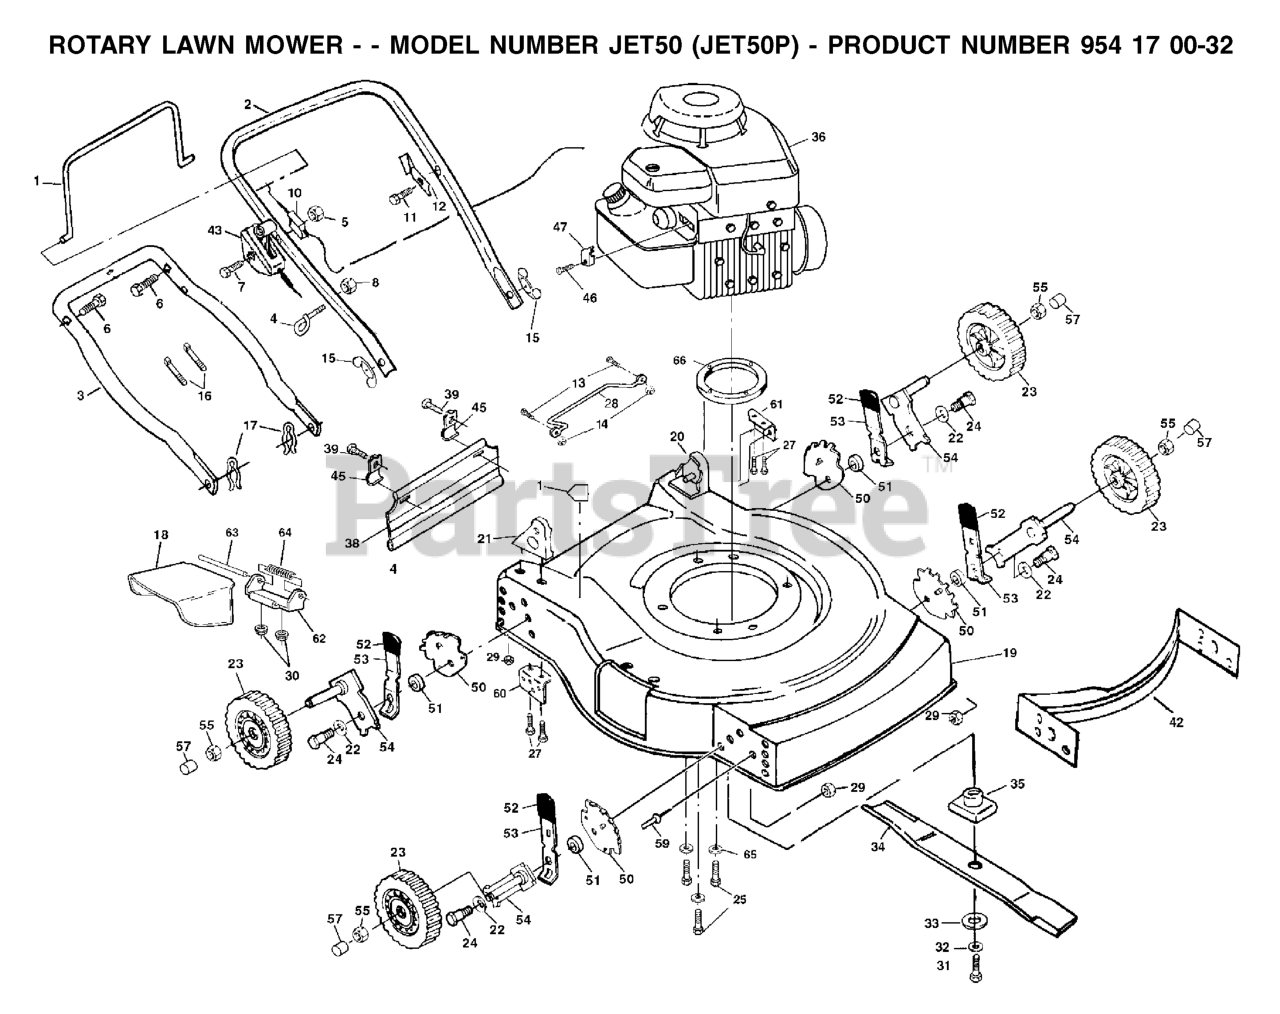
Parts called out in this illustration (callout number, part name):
1	CONTROL BAR
2	UPPER HANDLE
3	HANDLE
4	ROPE, GUIDE
5	NUT
6	HANDLE BOLT
7	SCREW 1/4-20 X 2.12
8	NUT
10	CABLE.MZR.51.RT.SP./PU.
11	TAPPING SCREW
12	BRACKET UPSTOP
13	REPL BY 817 02 10-08
15	NUT WING PM
16	TIE GUIDE
17	HAIRPIN COTTER
20	HANDLE BRACKET ASM. LH
21	HANDLE BRACKET ASM. RH
22	WASHER.BELLEVILLE (3 2 LB)
23	WHEEL
24	BOLT
27	SCREW.5/16-18X3/4
29	LOCKNUT PM
30	NUT
31	SCREW, HEX HD 3/8-24 X 1-3/8
32	LOCKWASHER
33	WASHER,HARDEN
34	20" Blade
35	BLADE ADAPTOR
38	REAR SKIRT
39	TAPPING SCREW
41	DECAL MOWER CUT/FINGER
43	THROTTLE CONTROL
45	BRACKET DEFL PM
46	SCREW.HEX.HEAD.WASHER.10-16
47	CABLE CLAMP(ENGINE)
50	WHEEL ADJUST BRACKET
51	RP SPACER HT ADJ
53	SELECTOR SPRING
54	AXLE, REAR
55	HEX FLANGE LOCKNT
59	RIVET BLIND
60	Bracket Support (Right)
61	BRKT SUPPORT(L)
62	BRACKET PM
63	ROD.HINGE.COMBI-C
